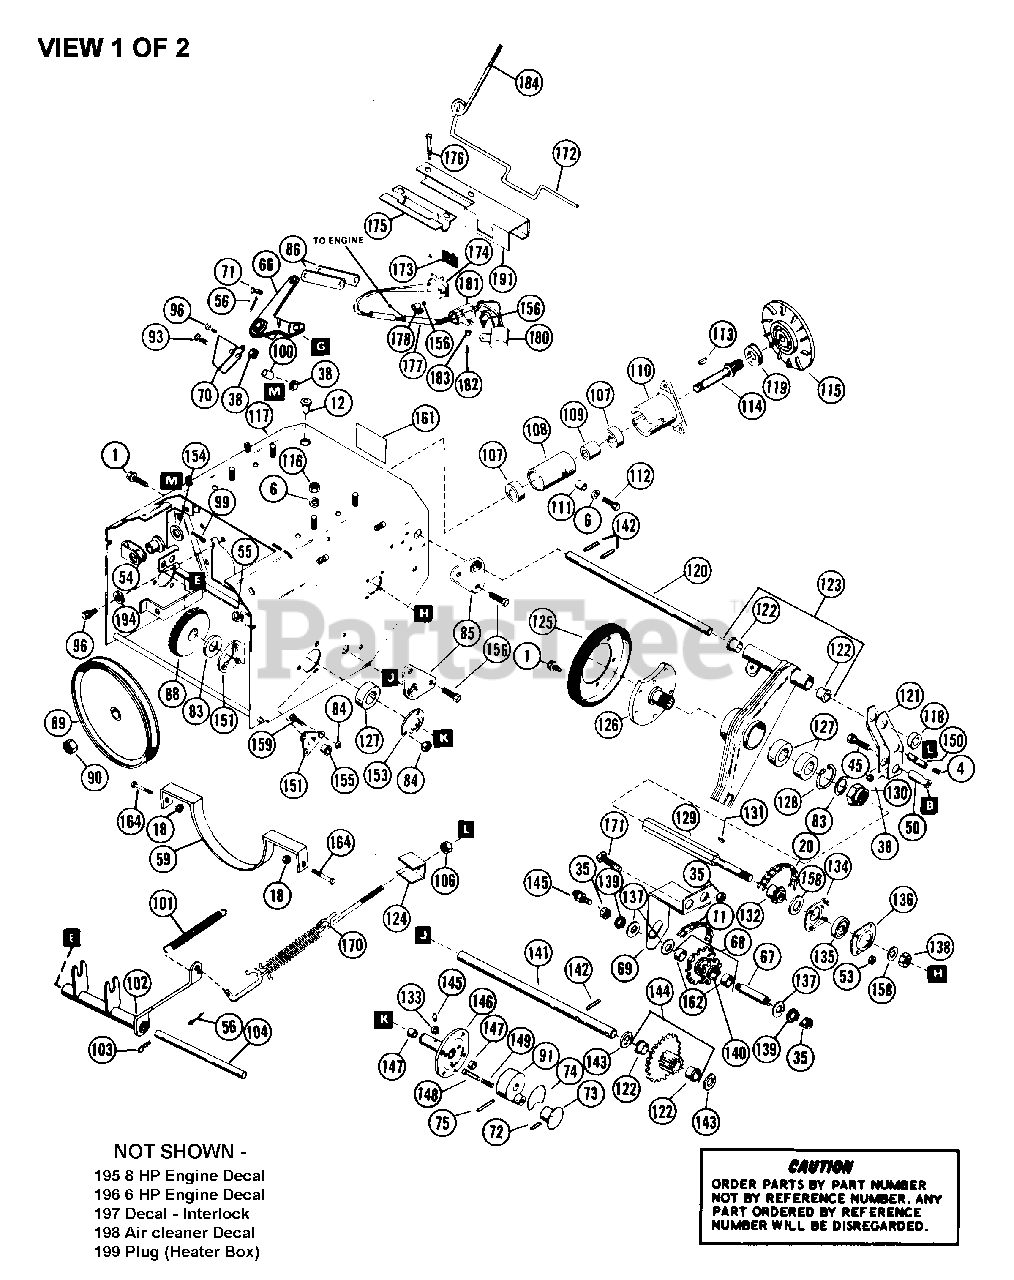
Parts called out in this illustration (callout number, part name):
1	BLT-SERHFWH .31-18X.50 PL
2	OUTER BELT GUARD
3	V-BELT, 3L-RAW EDGE
4	SCR-SET .32-18X.38 SKHCUPNL OH
5	BLT-HEX .31-24X.75 PL GR5
6	WSHR-LK .312X.097 PL HVY
8	BELT FINGER
9	BLT-HEX .25-20X.63 PL GR2
10	WSHR-FL-STL .38X.875X.083 PL
11	PINION CHAIN
12	SNAP BUSHING-.437
13	ENGINE SHEAVE
14	KEY-STR .25X1.75X.25
15	COVER SERVICE ASSEMBLY
16	R H LOWER HANDLEBAR
17	UPPER HANDLEBAR
18	NUT-LK-CTR .250-20 PL
19	GRIP
20	IDLER CHAIN
21	TIRE & WHEEL ASSEMBLY GOODYEAR
21	TIRE 4.10/3.50X6 2PLY
21	WHL 6 IN O.D.
21	TUBE
21	TERRA TIRE & WHEEL ASSEMBLY
21	TIRE 16X6.50-8 2 PLY
21	WHL
22	BLT-HEX .25-20X1.50 PL GR5
23	SCR-MCH 10-24X.62 SLRH PL
24	PANEL DASH
26	THROTTLE CONTROL
27	CLUTCH ROD
28	L H LOWER HANDLEBAR
29	CLUTCH HANDLE
30	NUT-KEPS 10-24 PL
31	SCR-TAP 12-14X1.50 CROVH PL BT
32	HANDLE PIVOT
33	BLT-HEX .25-20X1.75 PL GR2
34	WSHR-LK .375X.115 HVY PL
35	NUT-HEX .375-16
36	SHIFT ROD UPPER
37	PIN-COTR .15 X 1.0 PL
38	NUT-LK .312-18 GR A PL
39	CONTROL HANDLE
40	SG-COMP ??X.44X?? WLD 10
41	SHIFT BALL
42	SHIFT RELEASE HANDLE
43	PIN-ROLL .188X1.75
44	ACUTATION SHAFT
45	BLT-HEX .31-18X.75 PL GR2
46	CLUTCH ROD
47	SG-COMP .072X.37X10.3 WLD 40
48	PIN-ROLL .125X.75
49	ATTACHMENT CLUTCH ROD
50	ROD ADAPTER
51	PIN-ROLL .156X.75
53	NUT-LK DUAL FACE 10-24 PL
54	BSHG-FLG .372X.500X.312X.625NY
55	NUT-RETNR .38-16 TINRMAN
56	PIN-COTR .09X.75 PL
57	COVER DECAL
58	PIN-COTR .12X.50 PL
59	BELT RETAINER
60	NUT-HEX .312-24 PL
61	LABEL SHIFT
62	IN OUT LABEL
63	THROTTLE CONTROL DECAL
64	DECAL WARNING
65	ROD LOWER SHIFT
66	LEVER - SHIFT ARM
67	REDUCTION SHAFT SERVICE ASSEMB
68	SPROCKET ASSEMBLY
69	SUPPORT
70	BRACKET SHIFT LEVER
71	CLEVIS PIN
72	PIN-ROLL .093X1.00
74	DIFFERENTIAL LOCK LABEL
75	PIN-GRV .250X1.75 TP C
76	BOTTOM COVER
77	HUB CAP
78	PUSHNUT
79	SPINDLE CUP
80	BLT-WHL .50-20X.75 GR5 PL
81	R H AXLE SHAFT
82	PIN-ROLL .188X1.25
83	WSHR-FL-STL .880X1.250X.062
84	NUT-LK-FLG .250-20 PL
85	SUPPORT, SHAFT
86	SHIFT LINK
87	BSHG-FLG.500X.625X.312X.750NY
88	DIFFERENTIAL ASSEMBLY
89	PLY-V 8.00 X 1.0 W/KEY CLARK
89	PLY-V 6.00 X .63 W/KEY CLARK
90	NUT-LK-NYL.625-18 PL
91	LOCKOUT HUB
92	IDLER ARM
93	BLT-HEX .31-18X3.00 PL GR2
94	IDLER
95	IDLER ARM
96	BLT-HEX .31-18X.50 PL GR2
97	WSHR-FL-STL .382X.812X.023 PL
98	WAVE WASHER .406X.750X.063FH
99	PIN-COTR .12X1.0 PL
100	SPACER .5 X .33 X 2.4
101	SG-TENS .080X.73X3.06 WLD 20
102	CLUTCH FORK
103	PIN-HAIR INT .08X.38X1.42 YWZC
104	ROD, FORK PIVOT
105	SPCR, BRG .315X.50X.688X.281
106	NUT-LK-NYL.312-18 PL
107	BRG-BALL .625X1.375X.44
108	SPINDLE HOUSING
109	BEARING SPACER
110	DRIVE SPINDLE HOUSING
112	BLT-HEX .31-18X1.00 PL GR 2
113	KEY-WDRF .125X.500X.203 SAE 3
114	SPINDLE
115	DRIVE PLATE
116	NUT-HEX .312-18
117	TRACTOR FRAME 8 HP
117	TRACTOR FRAME 6 HP
118	SPACER 1.00 X .64 X .38
119	DRIVE DISC SPACER 1.3X.76X.19
120	CARRIER SHAFT
121	CLUTCH ENGAGEMENT YOKE
122	BSHG-FLG .625X.750X.500X.875BR
123	DISC CARRIER SERVICE ASSEMBLY
124	ADAPTER SPACER
125	FRICTION DISC
126	FRICTION DISC HUB
127	BRG-BALL .876 X 1.750 X .50
128	RG-RTNG-INT 1.750X.062
129	HEX SHAFT
130	NUT-LK-NYL .875-14
131	KEY-WDRF .125X.625X.250 SAE5
132	9 TOOTH SPROCKET
133	WSHR-LK .250X.047 LT PL
134	BEARING FLANGE
135	BRG-BALL .500X1.38X.437
136	BEARING FLANGE
137	WSHR-FL-STL .382X.812X.062
138	NUT-LK-CTR .50-20 PL
139	WSHR-LK .375X.130
140	REDUCTION SPROCKET
141	PINION SHAFT
142	PIN-ROLL .156X1.00
143	WSHR-FL-STL .630X1.005X.062 PL
144	PINION AND SPROCKET ASSY.
145	SPIN DRIVE ZERK FITTING
146	L. H. AXLE ASSEM
146	L H AXLE ASSEMBLY
147	BSHG-SLV .562X.625X.625 BRZ
149	SG-COMP .028X.34X1.062 WLD75
150	ADAPTER
151	BEARING FLANGE
151	SUPPORT, BEARING
152	BLT-HEX .31-18X1.25 PL GR2
153	BEARING FLANGE
154	WSHR-FL-STL .380X.626X.033
155	BSHG-FLG.875X1X.625X1.250 BR
156	BLT-SERHFWH .25-20X.50 PL
157	WSHR-FL-STL .880X1.380X.062
158	WSHR-FL-STL .505X1.000X.062
159	SCR-SLTR-SERNK .25-20X.62 PL
160	BLT-HEX .31-18X2.00 PL GR2
161	3 HP ENGINE DECAL
162	BSHG-SLV .500X.625X.500 BR
163	BRACKET
164	BLT-HEX .25-20X.50 PL GR2
165	WSHR-LK .250X.077 HVY PL
170	SPRING ASSEMBLY
171	SCR-TAP .375-16X.75 HWH PL TR
172	SWITCH ACTUATOR
173	SWITCH BOOT
175	ROD RETAINER
176	SCR-TAP 10-24X.375 CRPH 1A
177	WIRING HARNESS
180	MODULE T SERVICE ASSEMBLY
181	CONNECTOR
182	BLT-HEX 10-24X.38 PL GR2
183	NUT-KEPS 10-24 PL
184	LOWER ROD INTERLOCK
185	NUT-HEX .250-20 PL
186	UPPER ROD INTERLOCK
187	PIN-COTR .06X.50
188	HANDLE INTERLOCK
189	PIN PIVOT
190	PUSH NUT, .25
191	SWITCH RETAINER
192	SPACER .50 X .32 X .42
193	WSHR-FL-STL.312X.734X.065PL
194	WSHR-LK-INT .313X.030 PL
195	8 H P ENGINE DECAL
196	6HP ENGINE DECAL
